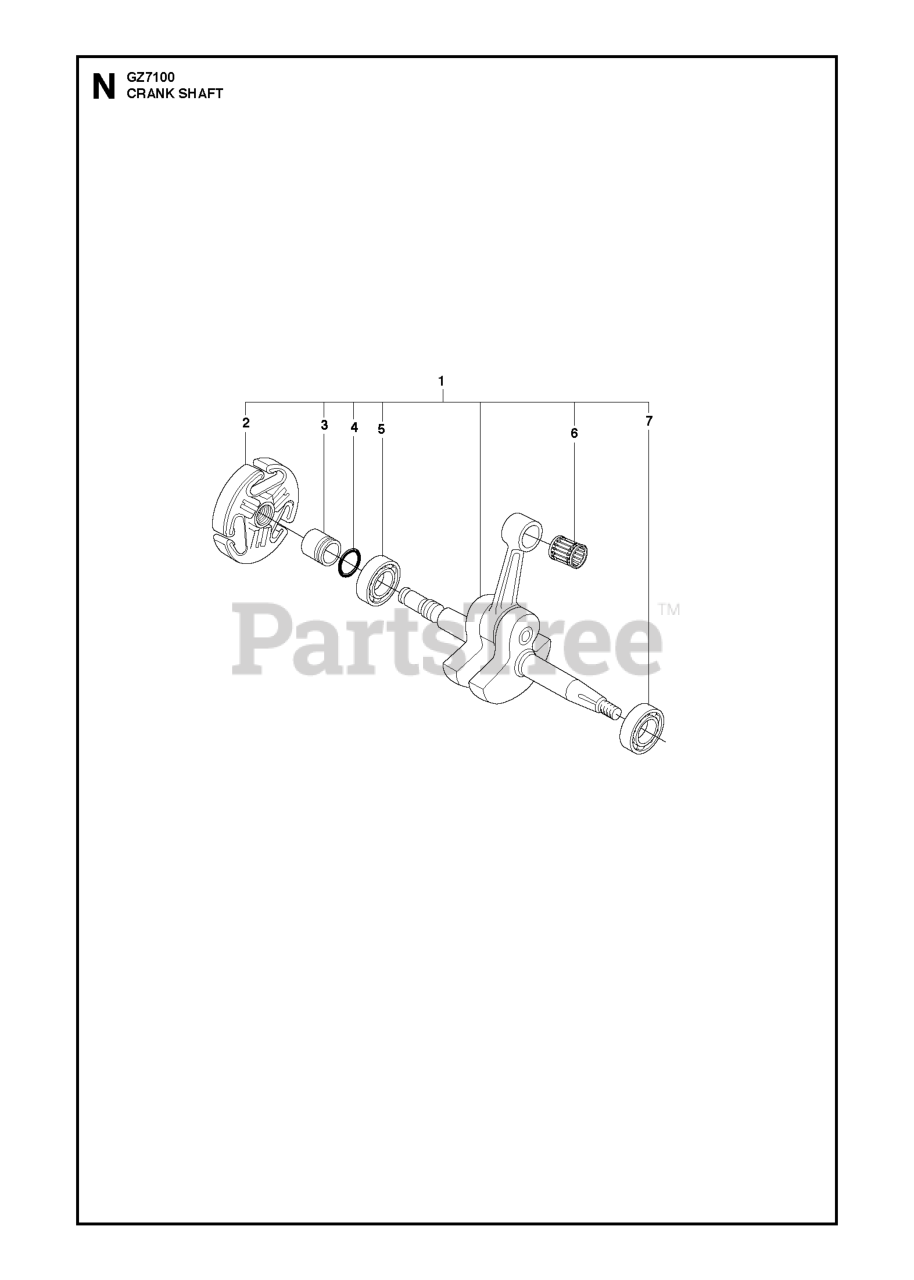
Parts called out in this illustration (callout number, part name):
1	CRANKSHAFT
2	CLUTCH ASSY M14X1.25-6H
3	SLEEVE
4	O-RING
5	BALL BEARING
6	NEEDLE BEARING PISTON PIN 12X1
7	BALL BEARING
